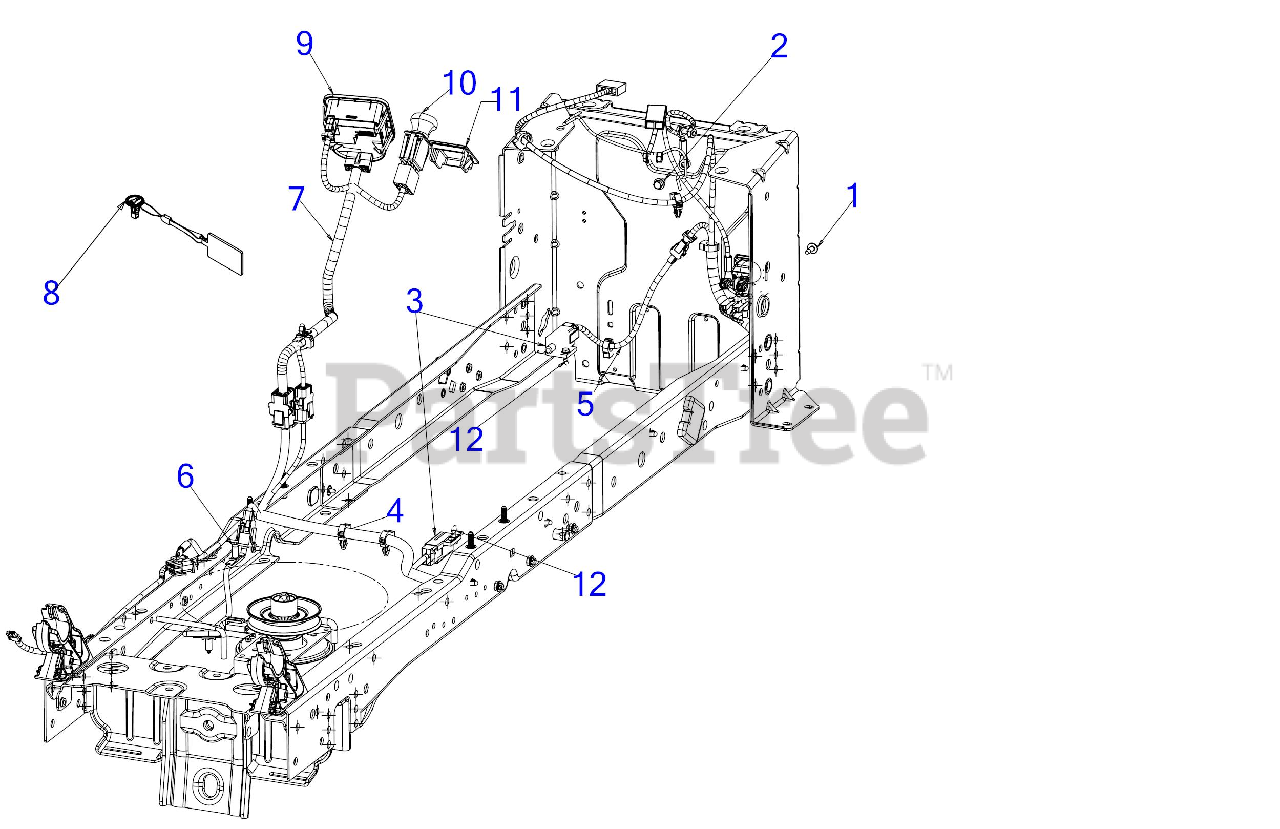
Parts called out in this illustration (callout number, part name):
1	SCREW M6-1 x .625
2	SCREW 1/4-20X.625
3	INTERLOCK SWITCH (NO/NC)
4	REVERSE HARNESS
5	CLUTCH HARNESS 11"
6	MAIN HARNESS E-PTO/PBS/RMC
7	DASH HARNESS E-PTO/PBS/RMC
8	PBS KEY
9	MODULE-PBS/HRMTR/SVC MNDR/BT
10	PTO SWITCH (YELLOW KNOB)
11	DASH HOUR METER PLUG
12	SHOULDER SCREW
